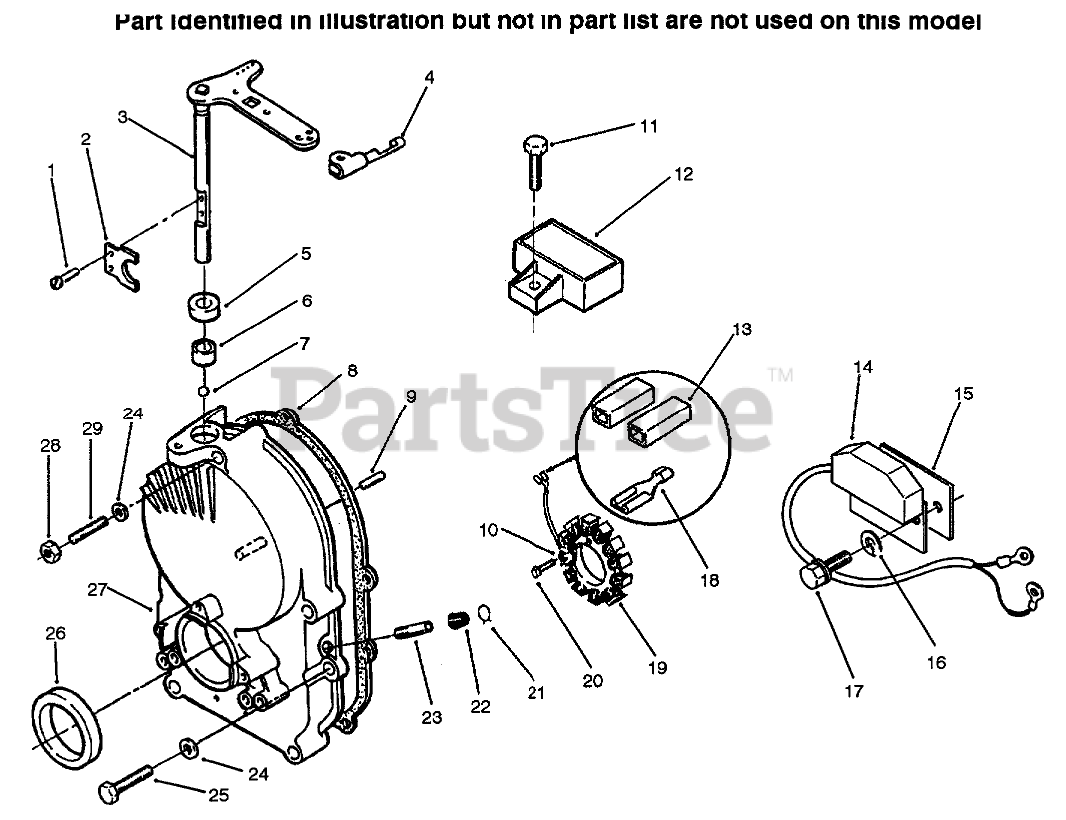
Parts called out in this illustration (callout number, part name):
1	SCREW-PAN HD
3	SHAFT AND ARM
4	RETAINING CLIP
6	BEARING
8	GEAR CASE MTG GASKET
9	PIN-DOWEL
10	WASHER-LOCK
11	SCREW-HWH
12	REGULATOR
13	BODY-TERM. CONNECTOR KIT
14	CONTROL-IGNITION
15	INSULATOR-IGN MODULE
16	WASHER-LOCK
17	Bolt
18	TERMINAL
19	KIT - STATOR
20	Screw-HH
21	CLAMP
22	CAP-FUEL OUTLET
23	TUBE-PORT, VACUUM
24	WASHER
25	HEX-HEAD CAP SCREW
27	GEAR-CASE KIT
28	NUT-GEAR COVER
29	STUD-GEAR COVER
